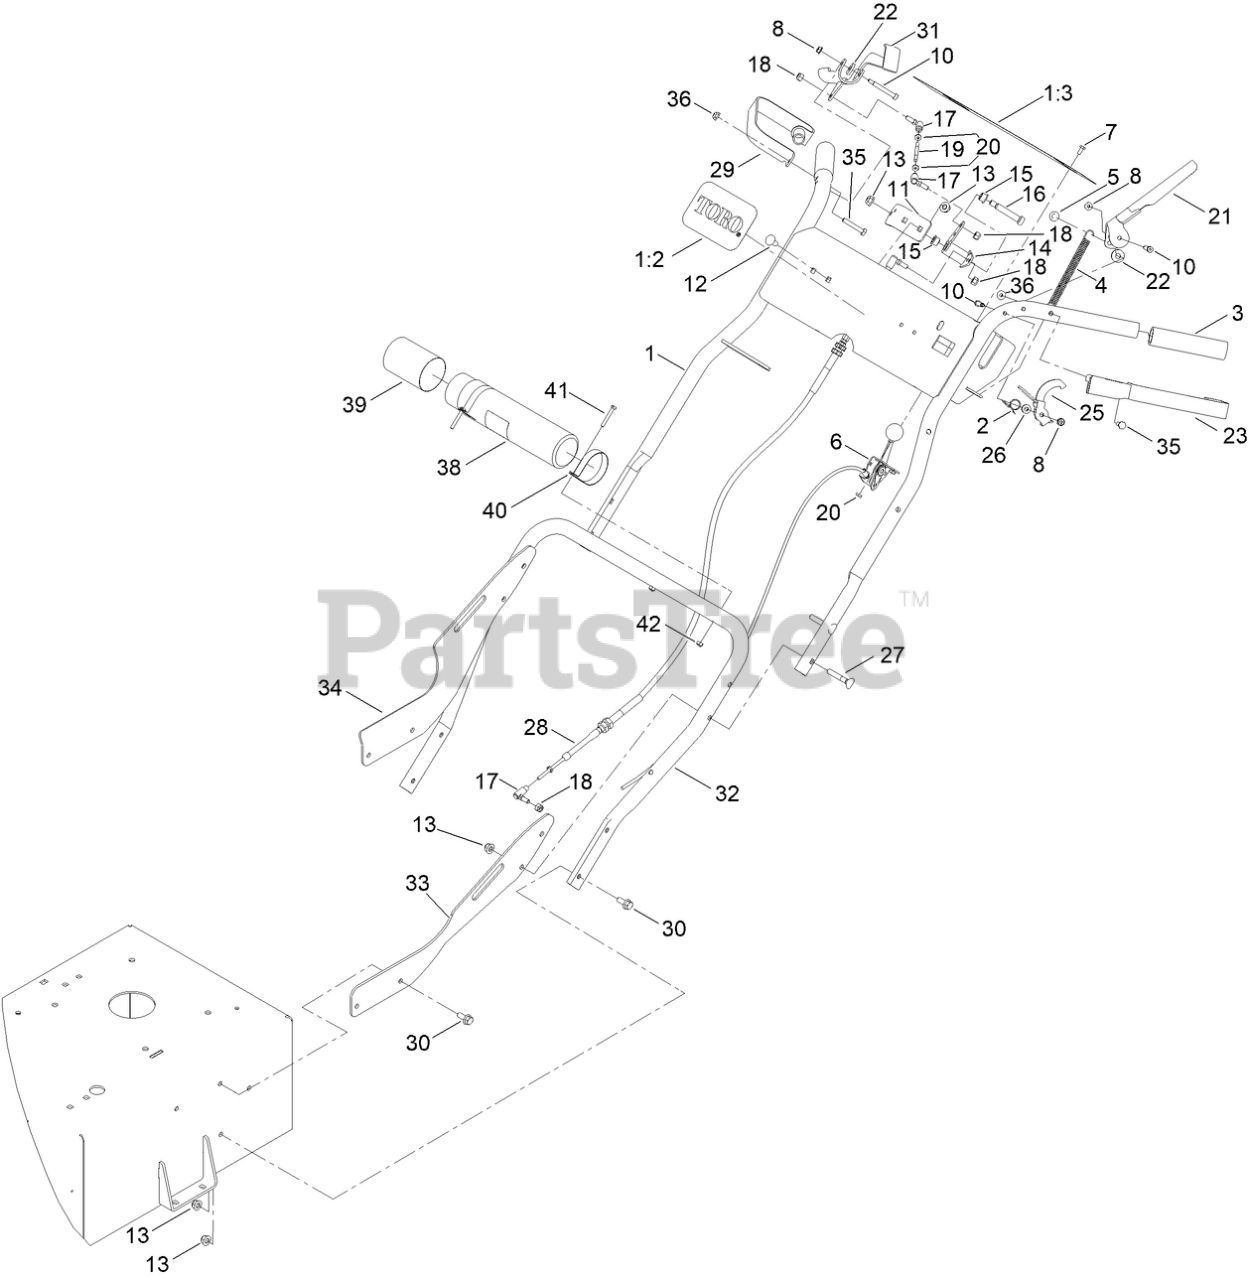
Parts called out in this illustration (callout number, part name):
1	HANDLE ASM
1:3	DECAL-OPERATION, SAFETY
2	SPRING
3	GRIP-FOAM
4	SPRING
5	NUT-PUSH
6	CABLE-THROTTLE
7	SCREW-HH
8	NUT-LOCK, FLANGE
10	BOLT-SHOULDER
11	MOUNT-BELL CRANK
12	BOLT-CARR
13	NUT-HF, NI
14	BELL CRANK ASM
15	BUSHING
16	SCREW-SHOULDER
17	BALL JOINT ASM
18	NUT-LOCK
19	LINK-CONTROL
20	NUT-HEX
21	HANDLE-CLUTCH
22	WASHER-FLAT
23	GUARD-KNUCKLE
25	LOCKOUT
26	SPACER
27	SCREW-HANDLE
28	CABLE-TRACTION
29	GUARD- KNUCKLE
30	SCREW-HHF
31	HANDLE-TRACTION
32	HANDLE-LOWER
33	BRACE-HANDLE [BLACK]
34	BRACE-HANDLE [BLACK]
35	SCREW-HH
36	NUT-HF
38	TUBE-MANUAL
39	CAP-HOUSING
40	CLAMP-R
41	SCREW-SHH
42	NUT-LOCK, NI
